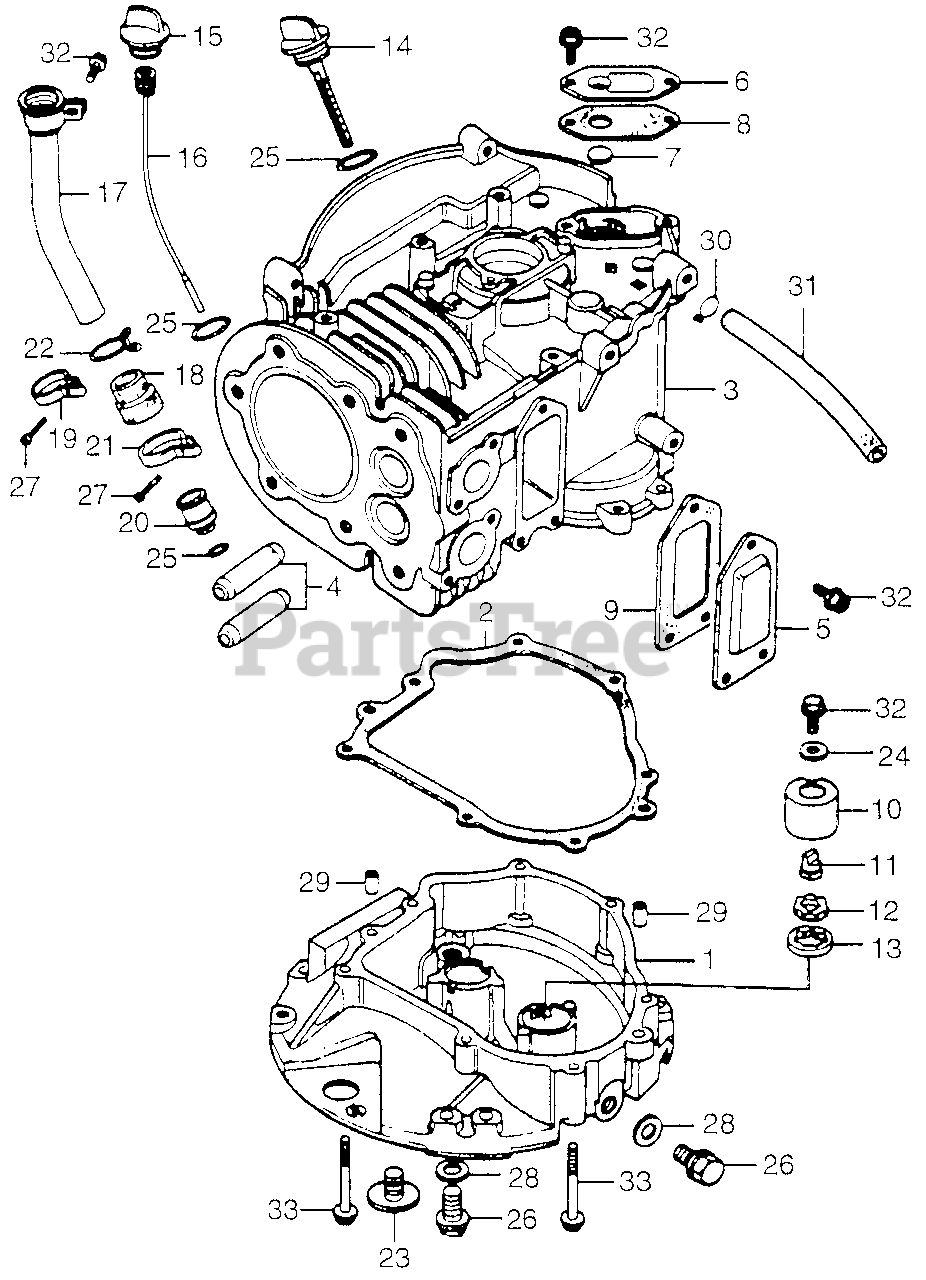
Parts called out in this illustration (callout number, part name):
1	PAN, OIL
2	GASKET, OIL PAN
3	CYLINDER
4	GUIDE, VALVE (OS) (NOT AVAILABLE)
5	COVER, TAPPET
6	CAP, BREATHER CHAMBER (NOT AVAILABLE)
7	VALVE, BREATHER
8	GASKET, BREATHER CAP (NOT AVAILABLE)
9	GASKET, TAPPET COVER
10	BODY, OIL PUMP
11	SHAFT, OIL PUMP
12	ROTOR, OIL PUMP (INNER)
13	ROTOR, OIL PUMP (OUTER)
15	CAP, OIL
16	DIPSTICK, OIL
17	PIPE, OIL
18	RUBBER, OIL JOINT
19	BAND, CONNECTING TUBE
20	JOINT, OIL PIPE
21	BAND, CONNECTOR
22	CLIP, AIR HOSE (27) (NOT AVAILABLE)
23	BOLT, SPECIAL (12MM)
24	WASHER (6MM)
25	O-RING (15.8X2.4) (SHOWA)
26	BOLT, DRAIN PLUG (12MM)
27	SCREW, PAN (5X12)
28	WASHER, DRAIN PLUG (12MM)
30	CLIP, TUBE (B10)
31	BULK HOSE, VACUUM (5.5X3000) (5.5X105)
32	BOLT, FLANGE (6X12)
33	BOLT, FLANGE (6X40)
